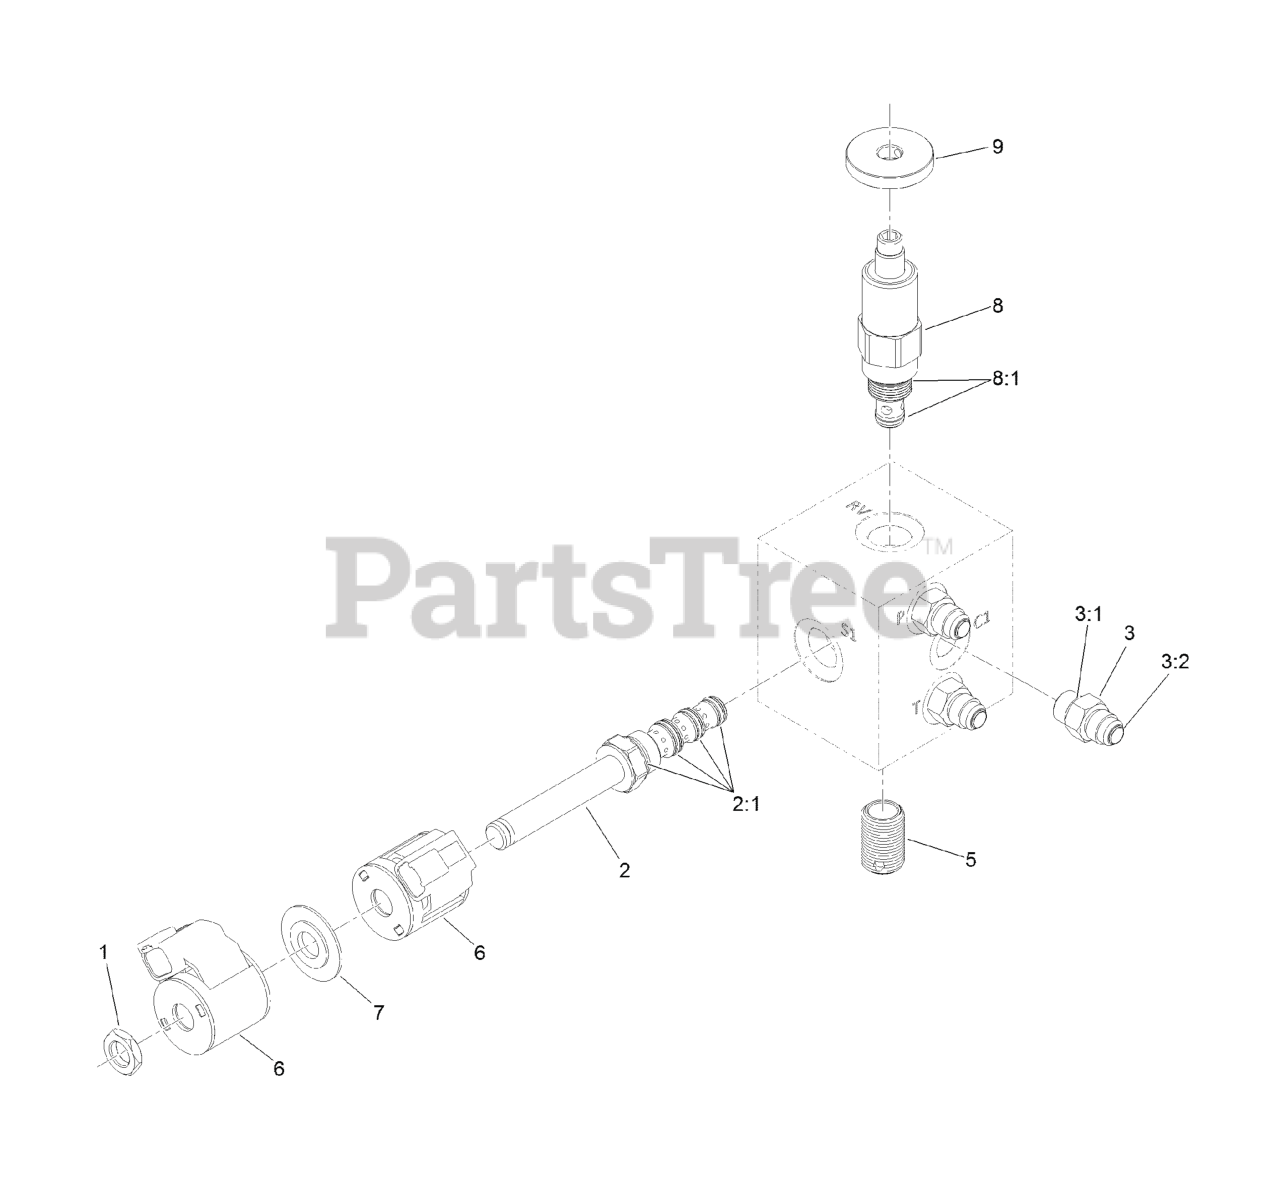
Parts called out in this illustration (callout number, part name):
1	NUT-COIL
2	VALVE-SOLENOID
2:1	Seal Kit
3	FITTING-STRAIGHT
3:1	BOSS O-RING
5	Nipple-Filter
7	Spacer-Coil
8	VALVE-RELIEF, POPPET TYPE
8:1	SEAL KIT
9	KNOB (1.5 DIA)
